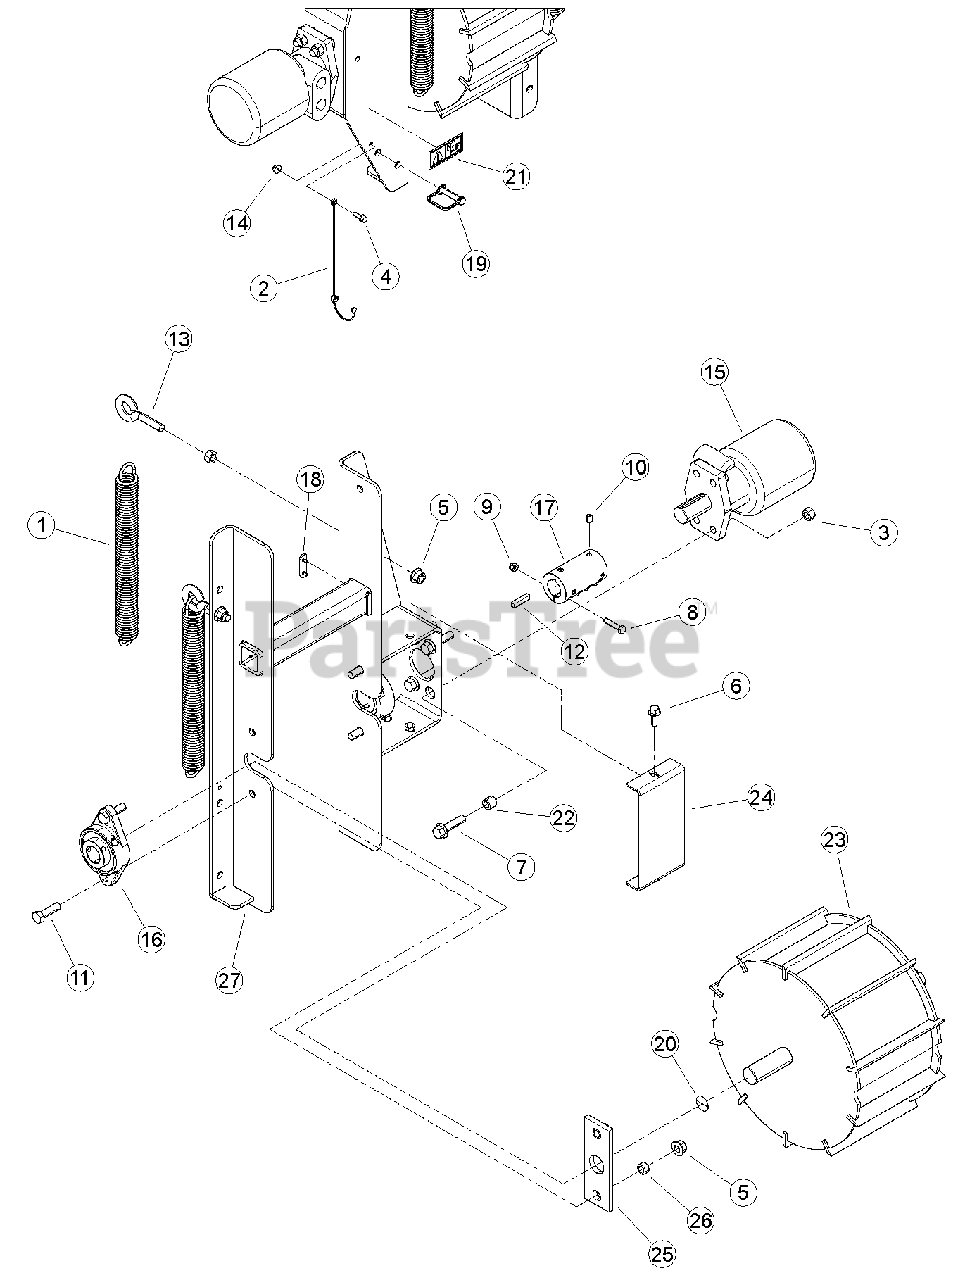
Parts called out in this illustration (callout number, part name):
1	SPRING, EXTENSION
2	LANYARD, NYLON
3	NUT, 1/2" CENTERLOCK GRB ZP
4	BOLT, 1/4-20 X 3/4 HWH GR5 CZP
5	NUT, 1/2-13 NYLOCK FLANGE
6	BOLT, 3/8 X 1 FLANGE NC
7	BOLT, 1/2-13 X 2 HWH GR5 CZP
8	BOLT, 5/16 X 1-1/2 GR5 HEX CPS ZP
9	NUT, 5/16" NE NYLOCK ZP
10	SET SCREW, 3/8 X 1/2 CUP PT SKT
11	BOLT, 1/2 X 1 3/4 GR5 HCPS NC ZP
12	KEY, 5/16 X 1-1/2 SQUARE
13	EYEBOLT, 1/2 X 2" ZP
14	NUT, 1/4-20 NYLOCK-FLANGE
15	MOTOR, 45 CU IN HYDRAULIC
16	BEARING, 1-1/4" DIA 2 BOLT FLANGE
17	COUPLER, 1-1/4 SHAFT
18	WEAR PAD, STD. SPRING HD FRONT
19	PIN, SNAP 3/8 X 1-1/2 USABLE LGH
20	DECAL, ROTATING SHAFT
21	DECAL, CRUSHING ISO
22	SPACER, 0.75 X 0.620
23	WELDMENT, TOP GRAB ROLLER
24	SHIELD, COUPLER
25	BEARING, SLIDE
26	SPACER, .75 OD X .5 ID X .37
27	WELDMENT, ROLLER SLIDE
